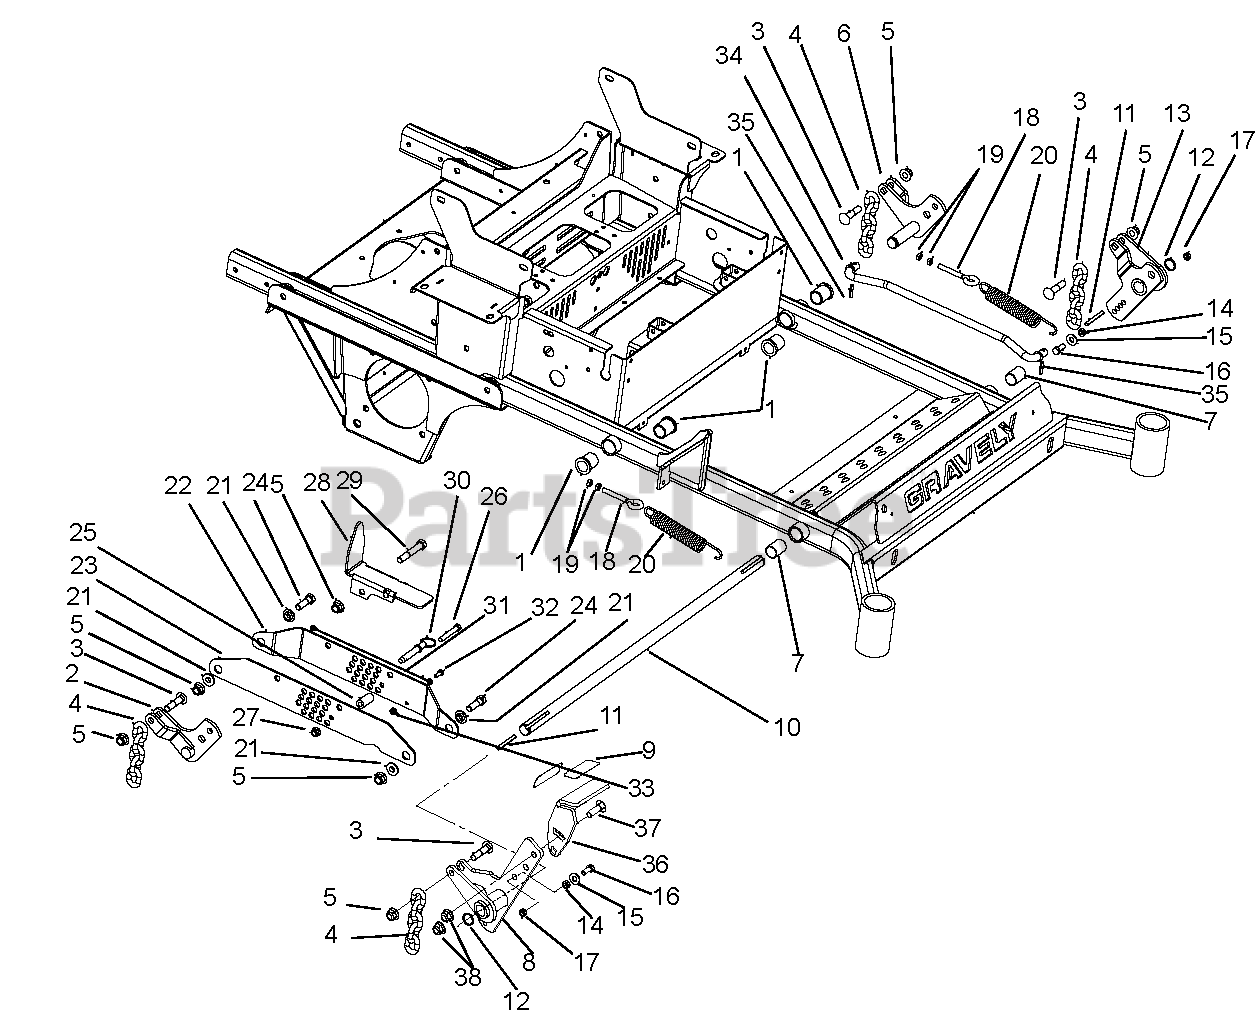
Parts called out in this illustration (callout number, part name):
1	Bushing, Flange 1.00 x 1.25 x 1.50 x 1.50
2	Weldment, Right Hand Rear Deck Lift
3	Bolt, Round Head Square Neck .50-13 x 2.25 G5YZ
4	Chain, 5 Link 3/8 Mower Lift
5	Nut, Locking Nylon-Flange .50-13
6	Weldment, Left Hand Rear Deck Lift
7	Bushing,1.00ID x 1.125OD x 1.50LG
8	Weldment, Adjustable Deck Foot Lift
9	Grip Pedal 1.50 x 3.00
10	Shaft, Front Mower Lift
11	Key, SQ .25 x 2.50 x .25 SAE
12	Ring, Retaining-E x T 1.00 x .078
13	Weldment, Front Left Hand Deck Lift
14	Bushing, Sleave .377 x .624 x .235
15	Washer, Flat Steel.438 x 1.00 x .083
16	Bolt, Hex .38-16 x 1.00 GR5
17	Nut, Locking Center-JAM .375-16
18	Bolt, Eye .375-16 x 2.50
19	Nut, Hex-JAM .375-16
20	Spring, Tension .162 x 1.25 x 8.25 WLD 25
21	Bushing, Flange .515 x .750 x .395 x 1.120
22	Bracket, Right Hand Lift/Cut Height Inboard
23	Bracket, Right Hand Lift/Cut Height Outboard
24	Bolt, Hex .50-13 x 1.75 GR5
25	Spacer, .375 x .750 x 1.54
26	Bolt, Hex .38-16 x 2.50 GR5
27	Nut, Locking Nylon-Flange .38-16
28	Weldment, Mechnical Lock-Up
29	Bolt, Hex .50-13 x 3.25 GR5
30	Pin, .50 x 2.00
31	Cable, 12.0 Lanyard, Nylon
32	Bolt, Hex .25-20 x .75 GR5
33	Nut, Locking Nylon-Flange .25-20
34	Rod, Lift Assist 19.35"
35	Pin, Roll .250 x 1.25 Stainless Steel
36	Adjustable Foot Lift Pedal, Black
37	Bolt, Round Head Square Neck .50 x 13 x 1.50 G5YZ
38	Nut, Locking, Nylon, Flange .50-13
